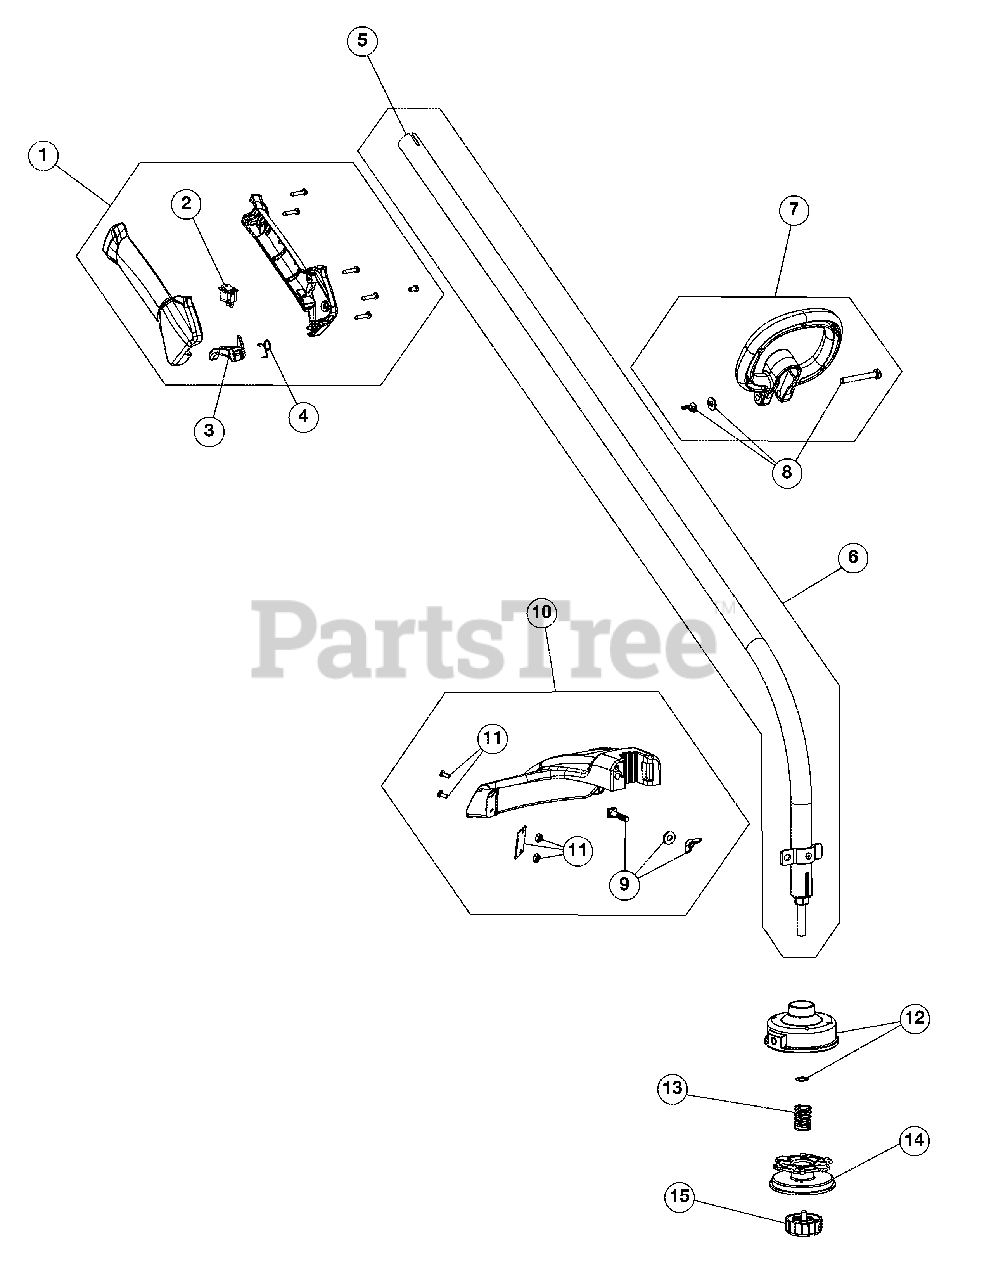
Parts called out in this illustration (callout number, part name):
1	Throttle Housing Assembly (Incl. 2-4)
3	Throttle Trigger
4	Throttle Trigger Spring
5	Flexible Drive Shaft
6	Drive Shaft Housing Assembly (Incl. 5)
7	D-Handle (Incl. 8)
8	D-Handle Hardware Assembly
9	Shield Mounting Hardware
10	Shield Assembly (Incl. 9 & 11)
11	Blade Assembly
12	Outer Spool w/Retainer
14	Inner Reel
15	Bump Head Knob Assembly
